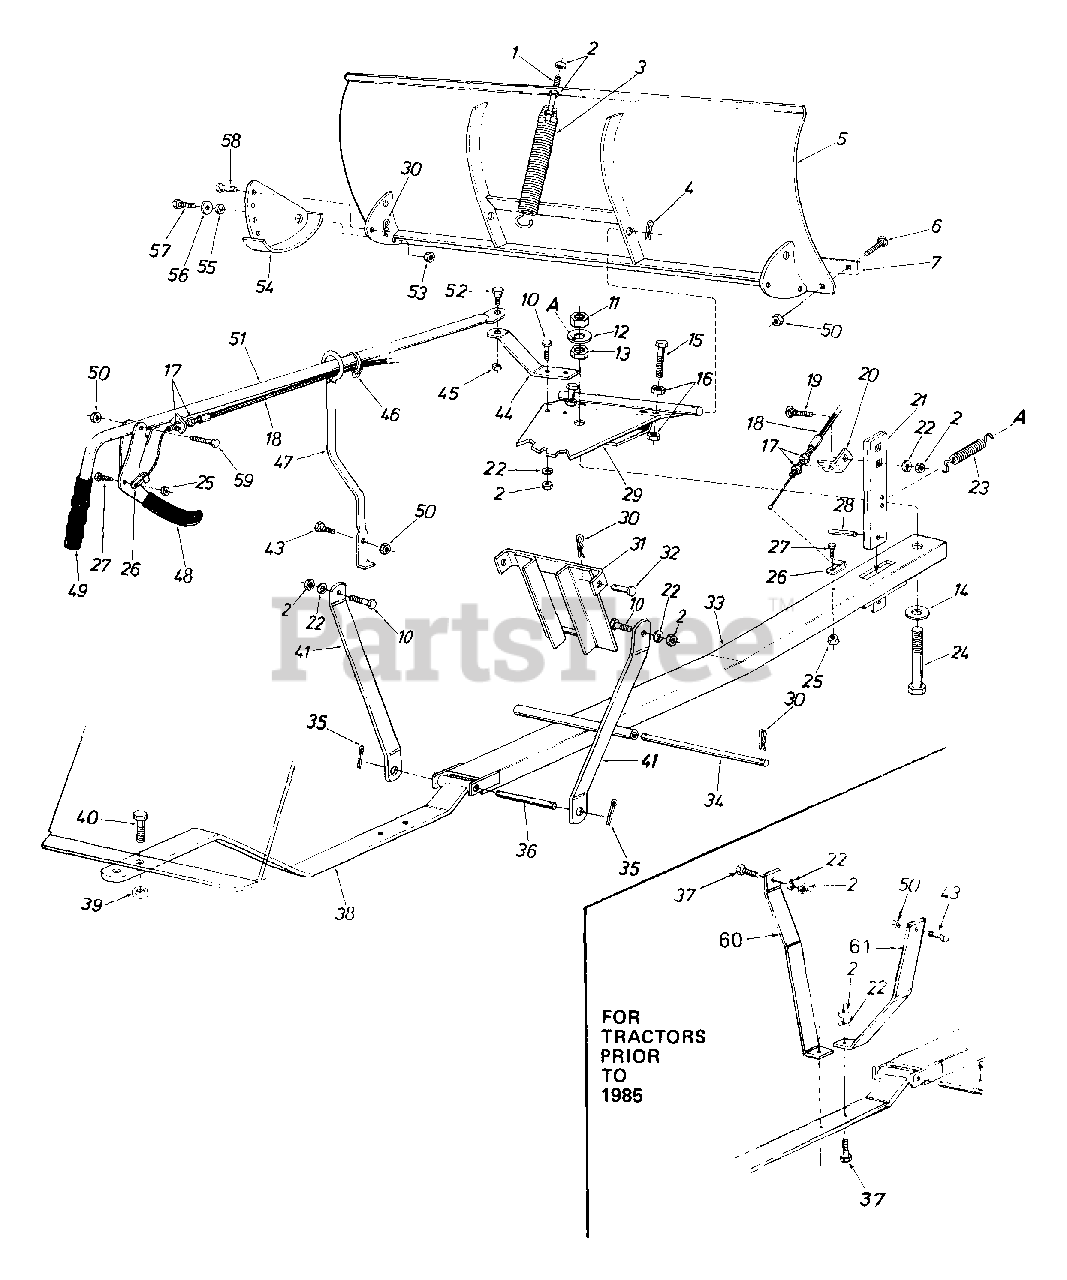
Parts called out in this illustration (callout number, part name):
1	Hex Scr. 3/8-16 x 4.50" Lg.
2	Hex Nut 3/8-16 Thd.
3	Blade Adjustment Spring
4	Hairpin Clip 5/32" Dia.
5	48" Blade Ass'y.
6	Carriage Bolt 5/16-18 x .75" Lg.
7	Wear Plate 48"
10	Hex Scr. 3/8-16 x 1.00" Lg.
11	Hex L.-Nut 3/4-10 Thd.
12	Fl.-Wash. .810" I.D. x 2.00" O.D. (Special)
13	Hex Jam Nut 3/4-10 Thd.
14	Fl.-Wash. .810" I.D. x 2.00" O.D.
15	Hex Scr. 1/2-13 x 2.00" Lg.
16	Hex Nut 1/2-13 Thd.
17	Hex Jam Nut 5/16-24 Thd.
18	Control Cable Ass'y.
19	Carriage Bolt 3/8-16 x 1.25" Lg.
20	Cable Guide Bracket
21	Angle - Lock Bar
22	L.-Wash. 3/8" I.D.
23	Angle Lock Spring
24	Hex Scr. 3/4-10 x 4.00" Lg. (Special)
25	Hex L-Nut 1/4-20 Thd.
26	Clevis Lanyard Fitting
27	Hex Scr. 1/4-20 x .75" Lg.
28	Roll Pin 1/4" Dia x 1.00" Lg.
29	Pivot Plate Ass'y.
30	Hairpin Clip 3/32" Dia.
31	Guide Bracket Ass'y.
32	Clevis Pin 1/2" Dia. x 1.00" Lg.
33	Push Bar Ass'y.
35	Cotter Pin 5/32" Dia. x 1.00" Lg.
37	Hex Scr. 3/8-16 x 1.25" Lg.
38	Hanger Bracket Ass'y.
39	Hex L.-Nut 5/8-11 Thd
40	Hex Scr. 5/8-11 x 1.50" Lg.
41	Hanger Link
43	Hex Bolt 5/16-18 x 1.00" Lg.
44	Blade Pivot Bracket
45	Hex L.-Nut 3/8-16 Thd.
46	Nylon Cable Tie
47	Tube Guide Ass'y.
48	Clutch Grip Ass'y.
49	Grip-3/4" Handle
50	Hex L-Nut 5/16-18 Thd.
51	Tube Handle Ass'y.
52	Shld. Scr.-Special 3/8-16 Thd.
53	Hex L.-Nut 3/8-16 Thd.
54	Skid Assembly
55	Spacer
56	Fl.-Wash. .385" I.D. x 1.00" O.D.
57	Hex Scr, 3/8-16 x .75" Lg.
58	Clevis Pin 5/16" Dia. x .75" Lg.
59	Hex Scr. 5/16-18 x 1.50" Lg.
60	Mounting Brkt. - L.H.
61	Mounting Brkt. - R.H.
